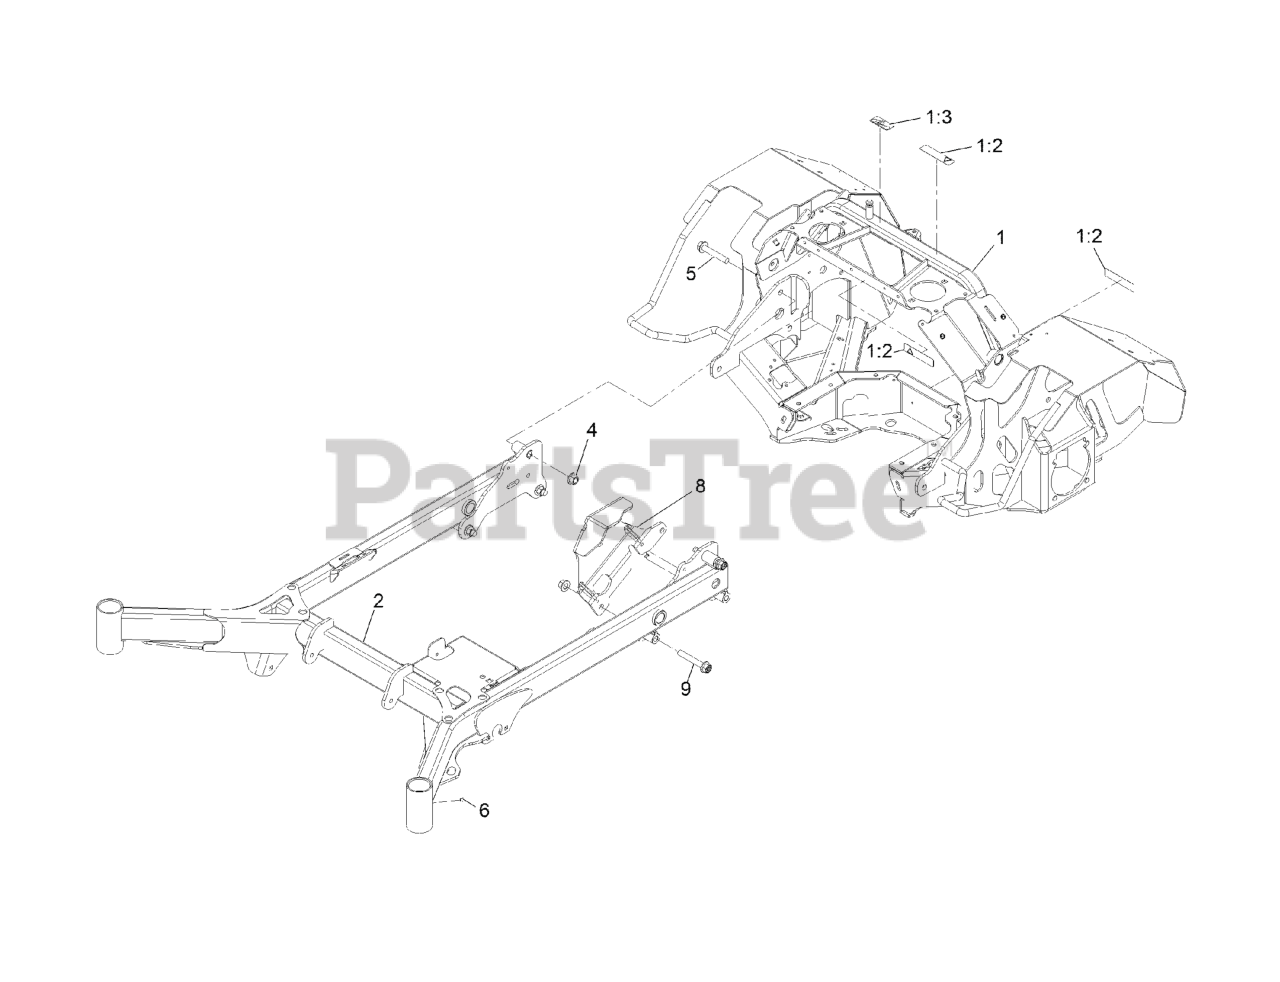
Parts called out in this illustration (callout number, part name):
1	ASM, REAR FRAME W/ DECALS
1:2	DECAL-WARNING
1:3	DECAL-BELT ROUTING HYD
2	WELD, FRONT FRAME, 60
4	Nut-Lock 1/2-13
5	SCREW-HF
8	WELD, FUEL MODULE
9	SCREW-HHF
